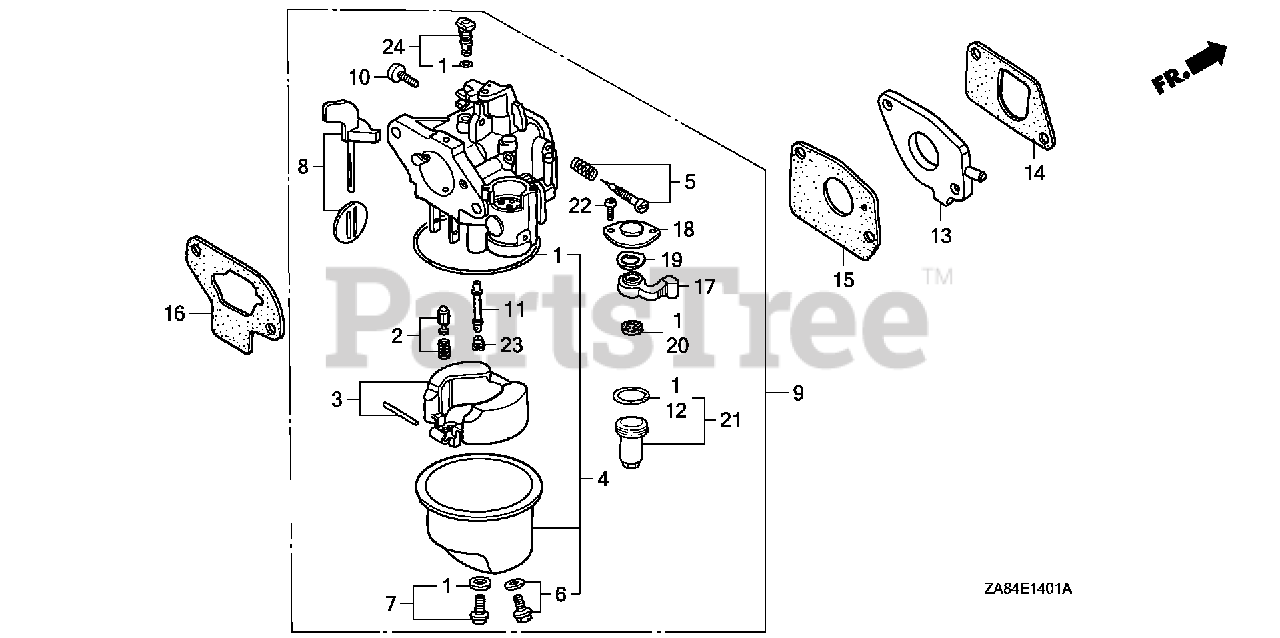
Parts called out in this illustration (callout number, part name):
1	GASKET SET
2	VALVE SET, FLOAT
4	CHAMBER SET, FLOAT
5	SCREW SET, PILOT
5	SCREW SET
6	SCREW SET, DRAIN
7	SCREW SET
9	CARBURETOR ASSY. (BF11E B)
9	CARBURETOR ASSY. (BF11H B)
10	SCREW, THROTTLE STOP
11	NOZZLE, MAIN
13	INSULATOR, CARBURETOR
14	GASKET, INSULATOR
15	GASKET, CARBURETOR
16	GASKET, AIR CLEANER
17	LEVER, VALVE
18	PLATE, LEVER SETTING
19	SPRING, VALVE LEVER
20	GASKET, VALVE
21	CUP, FUEL STRAINER
22	SCREW, PAN (3X6)
23	JET, MAIN (#50) Use from Engine SN BF11H B.
23	JET, MAIN (#52) Use from Engine SN BF11H B.
23	JET, MAIN (#55)
23	JET, MAIN (#50) Use up to Engine SN BF11E B.
23	JET, MAIN (#52) Use up to Engine SN BF11E B.
24	JET SET, PILOT (#35)
24	JET SET, PILOT (#38)
